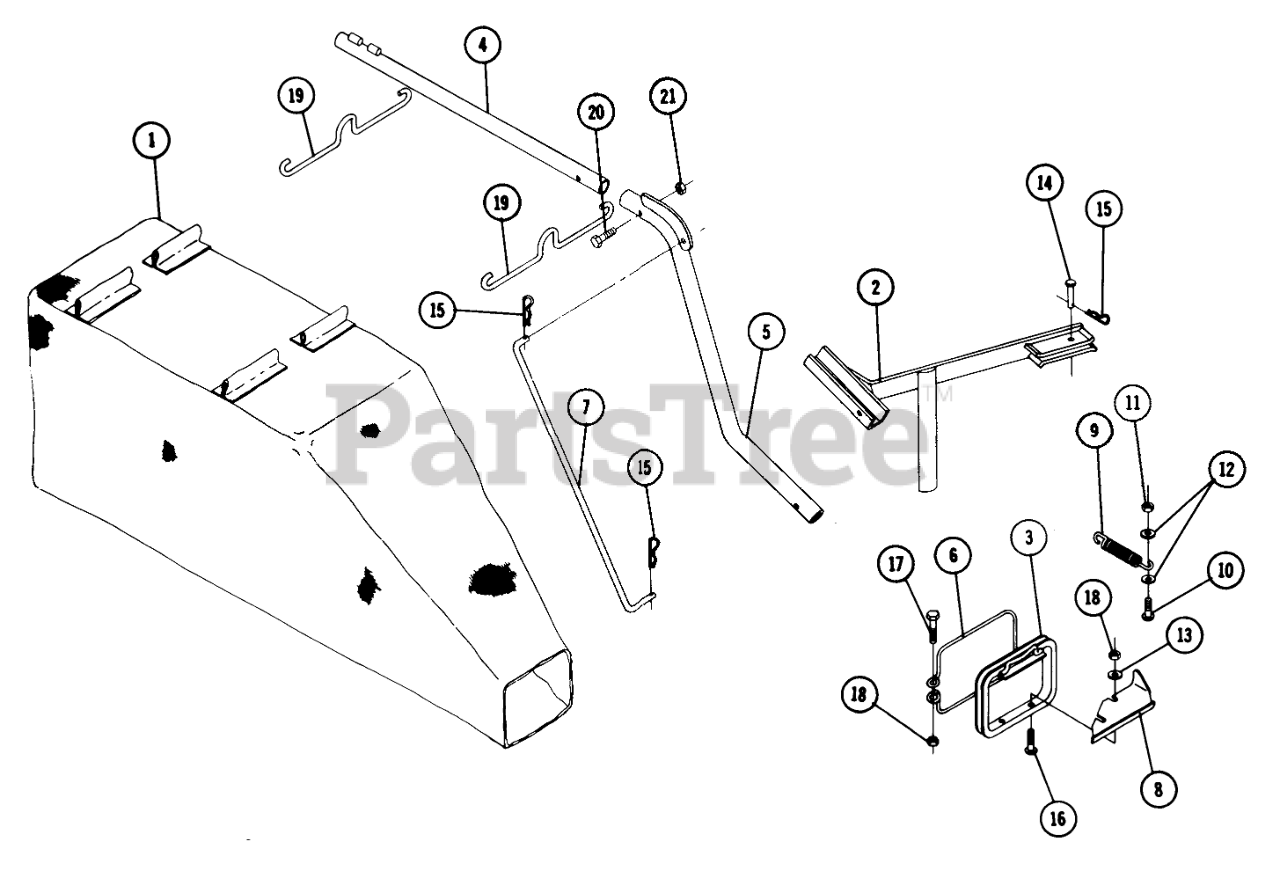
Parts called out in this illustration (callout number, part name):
2	Mounting Bracket
3	Bag Opening Frame
4	Upper Tube
5	Lower Tube
6	Hoop-Wire
7	Link
8	Bottom Plate
9	SPRING R
10	Bolt 3/8-16 x 1 Pan Hd.
11	3/8-16 E.S.
12	Washer
13	Washer
14	Clevis Pin
15	Hairpin
16	Bolt 1/4-20 x 3/8 PHCR
17	Bolt 1/4-20 x 2
18	Nut-Nylok
19	Hook
20	Bolt 5/16-18 x 11/4
21	Nut-Nylok
